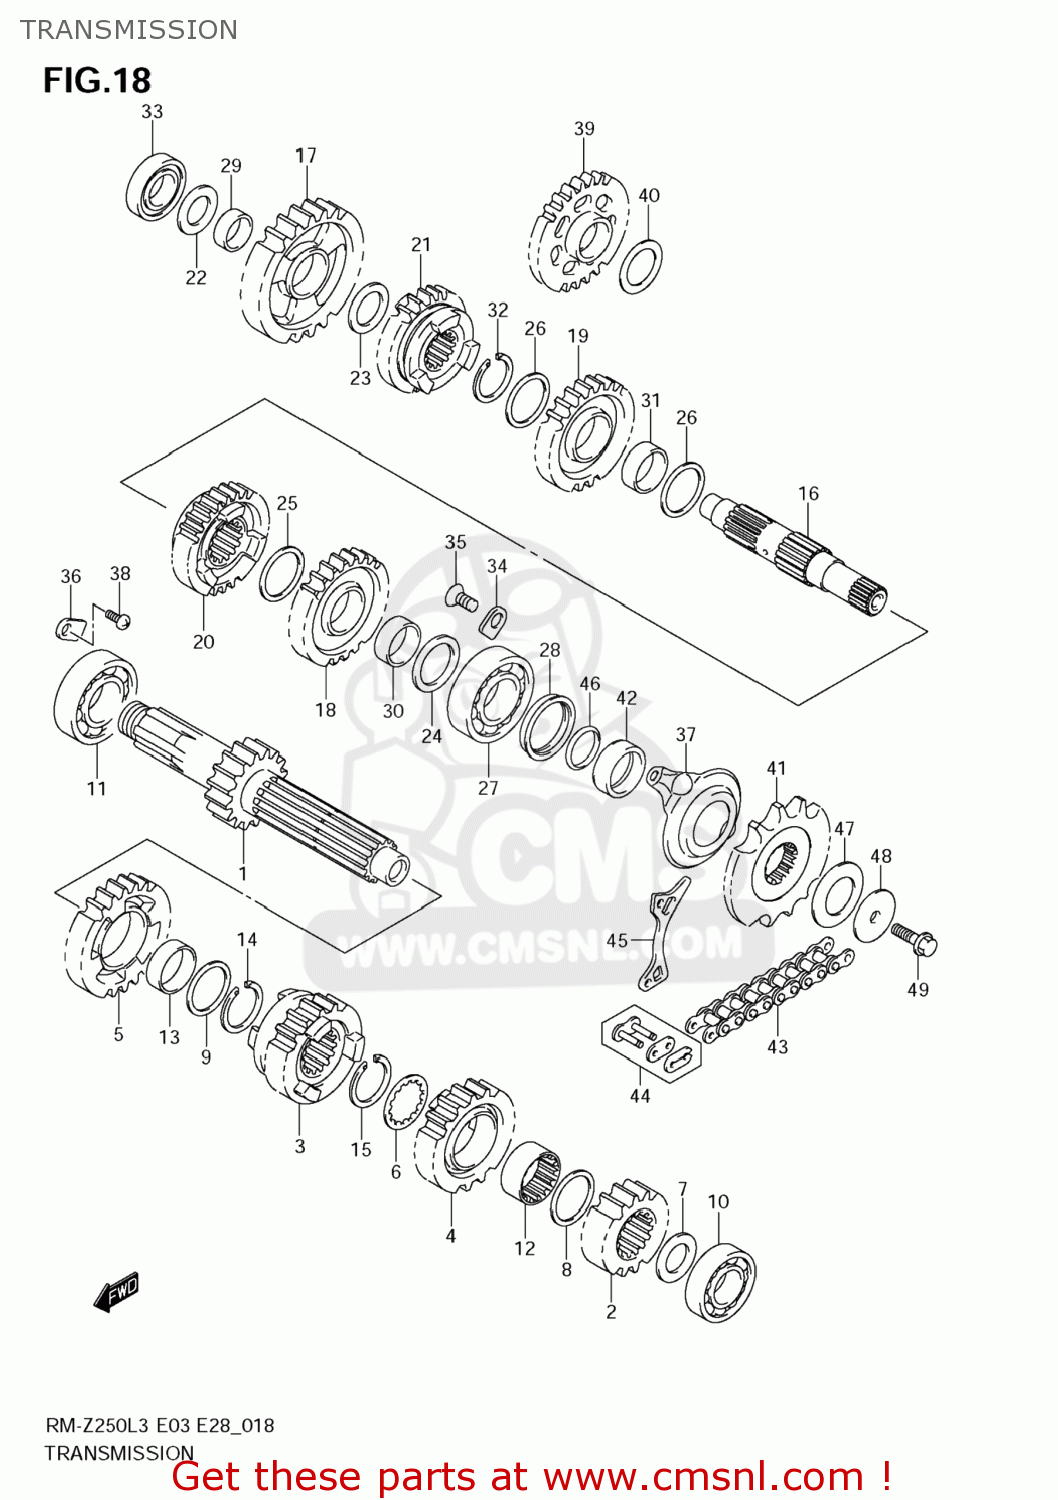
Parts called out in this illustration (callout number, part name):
1	SHAFT,COUNTER
2	GEAR,2ND DRIVE
3	GEAR,3RD DRIVE
4	GEAR,4TH DRIVE
5	GEAR,5TH DRIVE
6	WASHER,4TH DRIVE GEAR
7	SHIM(17X28X1)
8	SHIM(24X30X1)
9	SHIM(24X30X1)
10	BEARING(17X40X9.5)
11	BEARING(22X50X14)
12	BUSH,4TH DRIVE GEAR
13	BUSH,5TH DRIVE GEAR
14	CIRCLIP
15	CIRCLIP
16	SHAFT,DRIVE
17	GEAR,1ST DRIVEN
18	GEAR,2ND DRIVEN
19	GEAR,3RD DRIVEN
20	GEAR,4TH DRIVEN
21	GEAR,5TH DRIVEN
22	SHIM(17X28X1)
23	SHIM(20X28X1)
24	SHIM(22X30X1)
25	SHIM(24X30X1)
26	SHIM(24X30X1)
27	BEARING(22X52X15)
28	SEAL,OIL(28X38X7.5)
29	BUSH(20X24X10)
30	BUSH,2ND DRIVEN GEAR
31	BUSH,2ND DRIVEN GEAR
32	CIRCLIP
33	BEARING(17X40X12)
34	RETAINER,COUNTER BEARING,R
35	SCREW(6X12)
36	RETAINER
37	RETAINER,DRIVE SHAFT OIL SEAL
38	SCREW(6X12)
39	GEAR,KICK STARTER IDLE
40	WASHER,KICK IDLE
41	SPROCKET,ENGINE(13T)
42	SPACER,ENGINE SPROCKET
43	CHAIN,DRIVE
44	JOINT SET
45	PLATE,FR CHAIN GUIDE
46	D RING,SPROCKET SPACER
47	WASHER,ENGINE SPROCKET WAVE
48	WASHER,ENGINE SPROCKET
49	BOLT(8X30)
